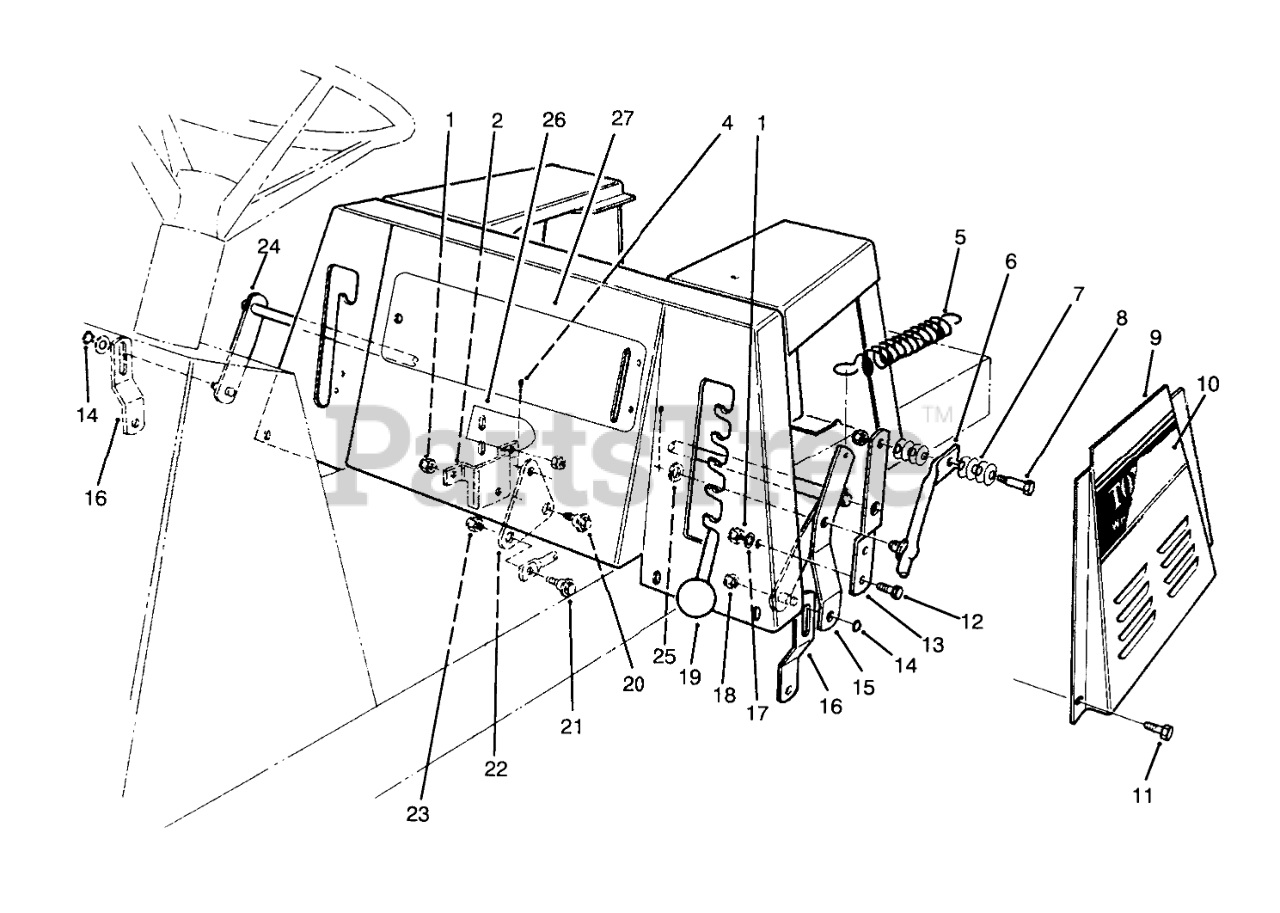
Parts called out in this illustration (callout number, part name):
1	NUT-LOCK, NI
2	BRKT-B.CRANK MTG
4	PIN-COTTER
5	SPRING-EXTENSION
6	HOC LEVER WA B
7	WASHER-BELLEVILLE
8	BOLT-SHOULDER
9	Panel L.H.-Base, Seat
10	DECAL - TORO 1232 LH
10	DECAL - TORO 1032 LH
11	SCREW-HH
12	SCREW-HH
13	Bracket
14	RING-RETAINING
15	Bracket-H.O.C., Engage
16	Link-Deck Suspension
17	WASHER-PLAIN
18	NUT-LOCK, NI
20	SCREW-SHOULDER
21	SCREW-SHOULDER
22	BELLCRANK
23	NUT-HEX
24	Arm
25	WASHER-FLAT
26	DECAL - USA
27	DECAL - CONTROL PANEL
